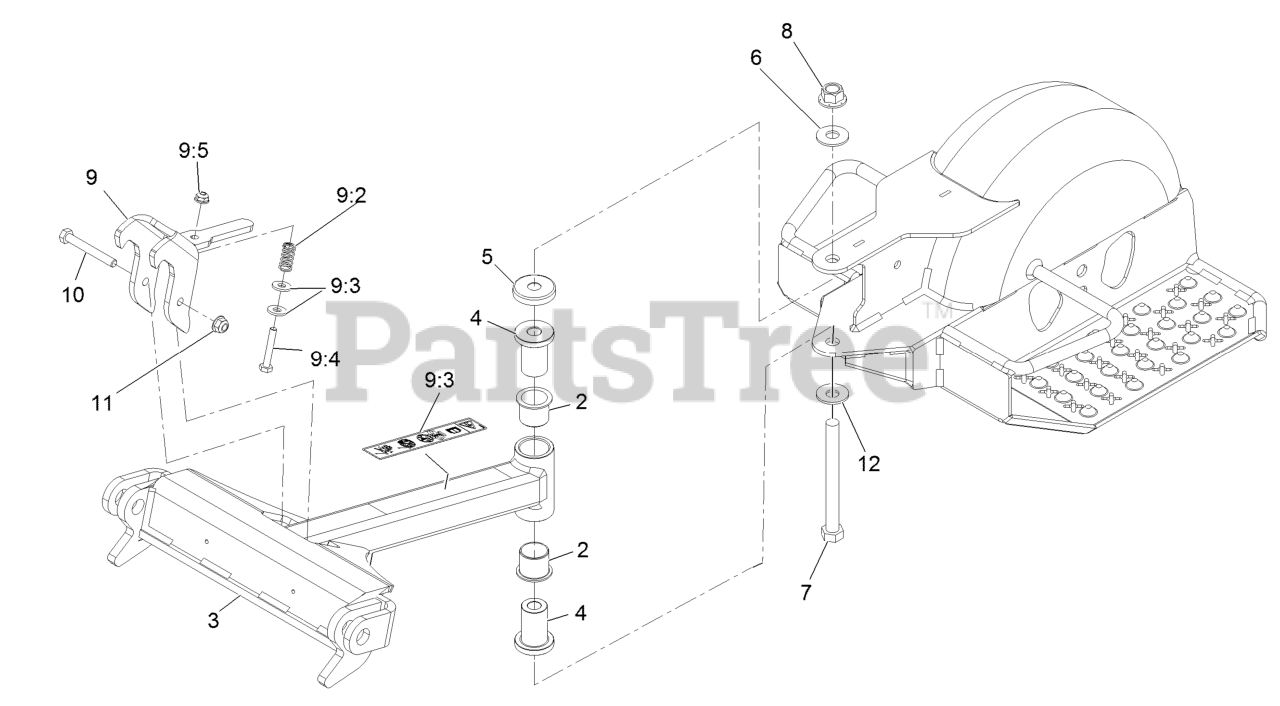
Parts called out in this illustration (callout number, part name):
2	Bushing-Pivot
3	Decal-Sulky Hazard
4	Spacer, Pivot
5	Cover, Dust
6	Washer-Belleville
7	Screw-HH 1/2-13 X 5
8	Nut-Lock 1/2-13
9	Transport Latch ASM
9:2	Spring, Compression
9:3	Washer-1/4 Std
9:4	Screw-HH
9:5	Nut-Nyloc 1/4-20 Flg
10	Screw-HH 5/16-18 X 2 1/2
11	Nut-Nyloc 5/16-18 Flg
12	Washer-Spring Disc 1/2
